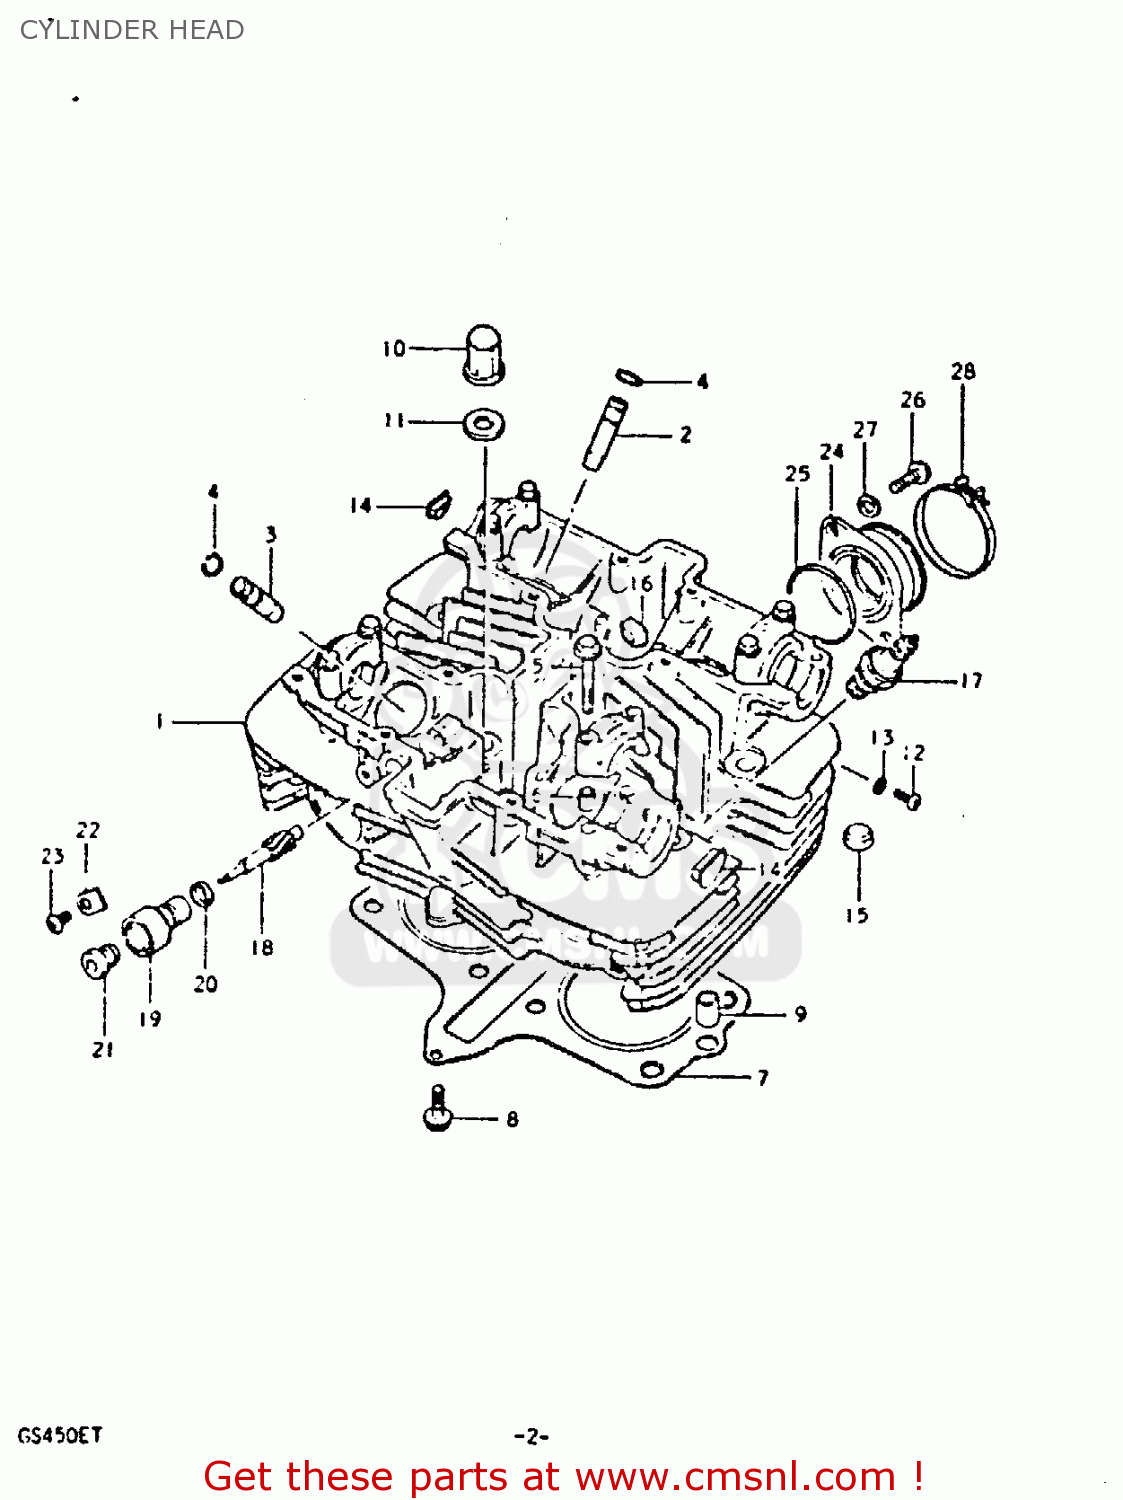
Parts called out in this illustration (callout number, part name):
1	HEAD ASSEMBLY,CYLINDER
2	GUIDE,INTAKE VALVE
3	GUIDE,EXHAUST VALVE
4	RING,SNAP
5	BOLT(6X39)
6	PIN(6.2X8X11)
7	GASKET,CYLINDER HEAD (MCA)
8	BOLT
9	PIN
10	NUT
11	GASKET (NAS)
12	SCREW
13	GASKET(5.3X9.3X1.2) (NAS)
14	PLUG
15	PAD,CYLINDER HEAD
16	PAD
17	SPARK PLUG
18	GEAR,TACHOMETER DRIVEN
19	SLEEVE,TACHOMETER DRIVE
20	SEAL,TACHOMETER DRIVEN
21	SEAL,OIL(5X12X8)
22	PLATE,TACH DRIVE GEAR SLEEVE
23	SCREW(5X12)
24	PIPE,INTAKE
25	O-RING (D:2.4 ID:39.7)
26	SCREW
27	LOCK WASHER
28	CLAMP
